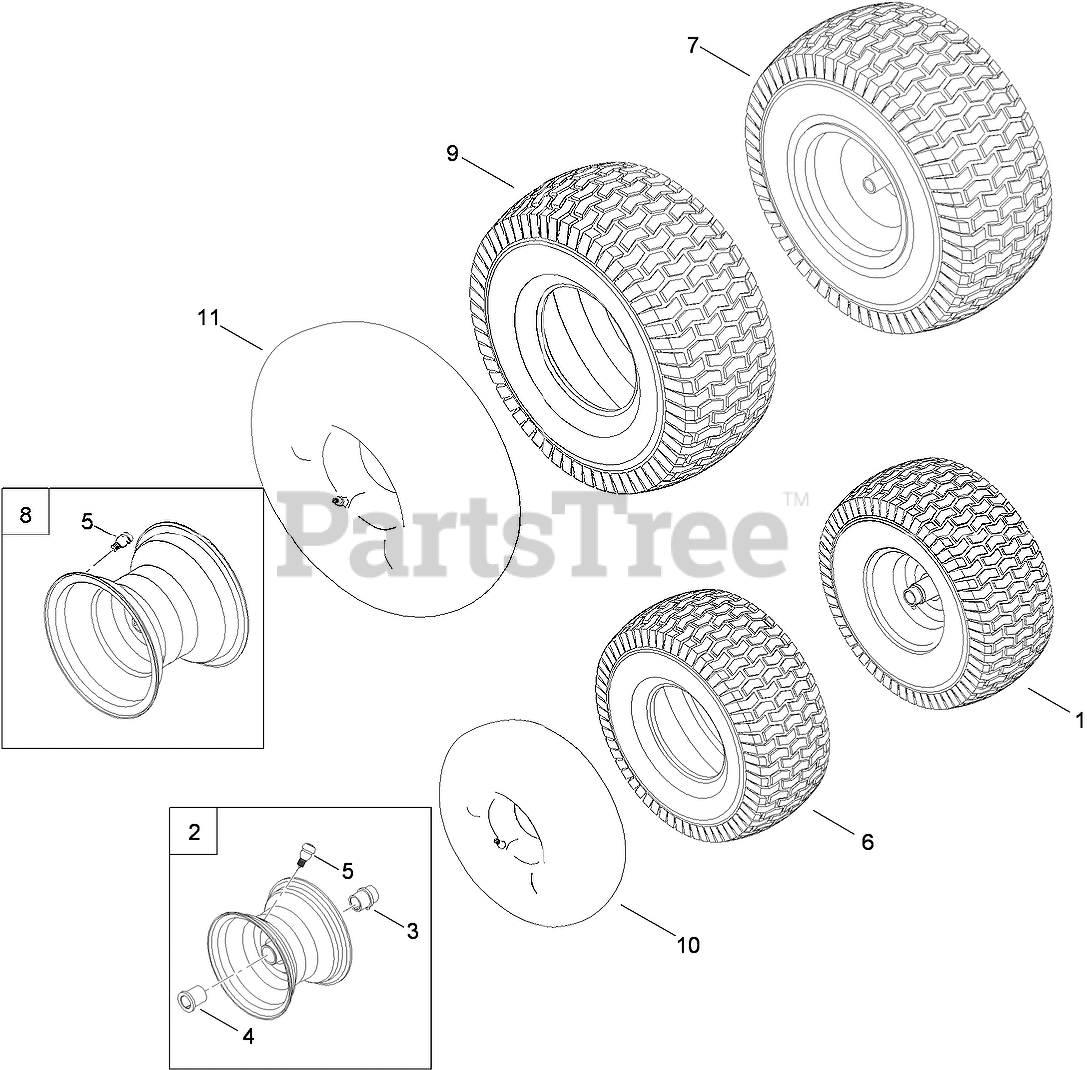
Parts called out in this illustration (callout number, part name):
1	FRONT WHEEL AND TIRE ASM
2	RIM ASM (W/BEARINGS)
3	BEARING-FLANGE (W/ZERK)
4	BEARING-FLANGE
5	VALVE-AIR, TUBELESS
6	TIRE-FRONT
7	REAR WHEEL AND TIRE ASM
8	RIM-WHEEL, REAR
9	TIRE-MULTI TRAC
10	TUBE-INNER
11	TUBE-INNER
